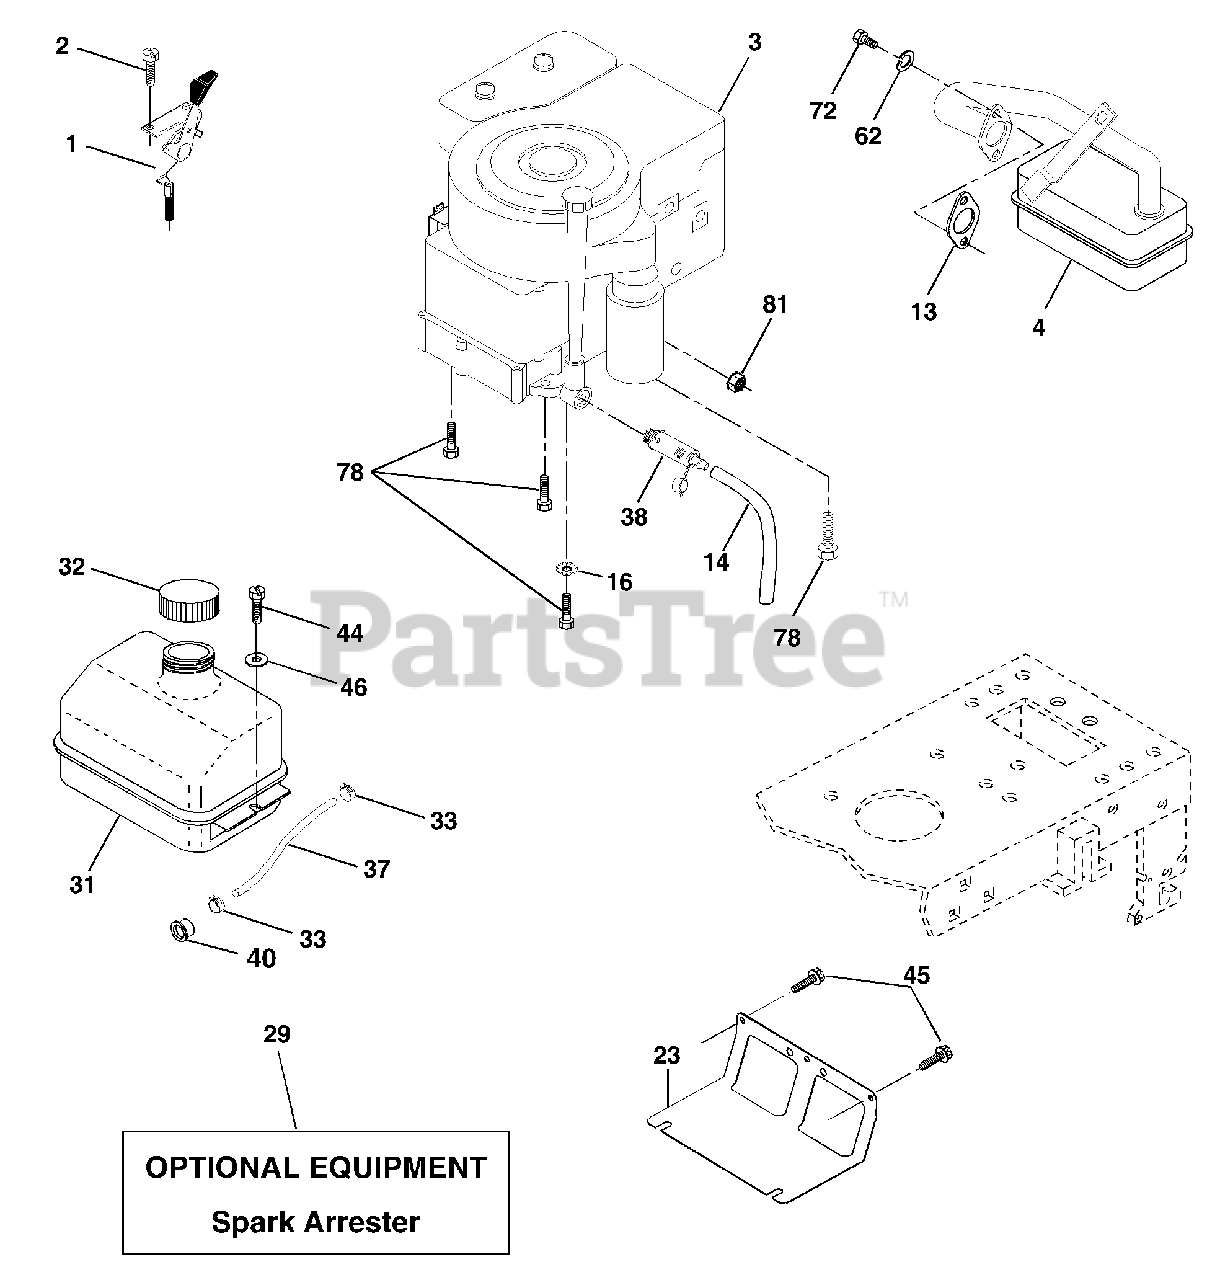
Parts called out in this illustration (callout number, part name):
1	Control Th/ch
2	Screw Hex Thd Cut 1/4-20 x 1/2
4	Muffler
13	Gasket Eng 1 313 Id Tin Plated
14	Tube Drain Oil Easy
16	Washer Lock Ext Tooth 3/8
23	Shield Browning
29	Kit Spark Arrestor (Flat Scrn)
31	Tank Fuel Front 1 25
32	Cap Asm Fuel
33	Clamp Hose Blk
37	Line Fuel 20"
38	Plug Drain Oil Easy
40	Bushing Snap Nyl Blk Fuel Line
44	Screw Hexwsh Thdrol 1/4-20 x 3/4
45	Screw Hex Wsh Thdrol 3/8-16
46	Washer 9/32 x 7/8 x 16 ga
62	Washer Lock Hvy Hlcl Spr 5/16
72	Screw Hexhd Cap 5/16-18 x 3/4
78	Screw 3/8-16 x 1-1/4
81	Nut Keps Hex 1/4-20 UNC
